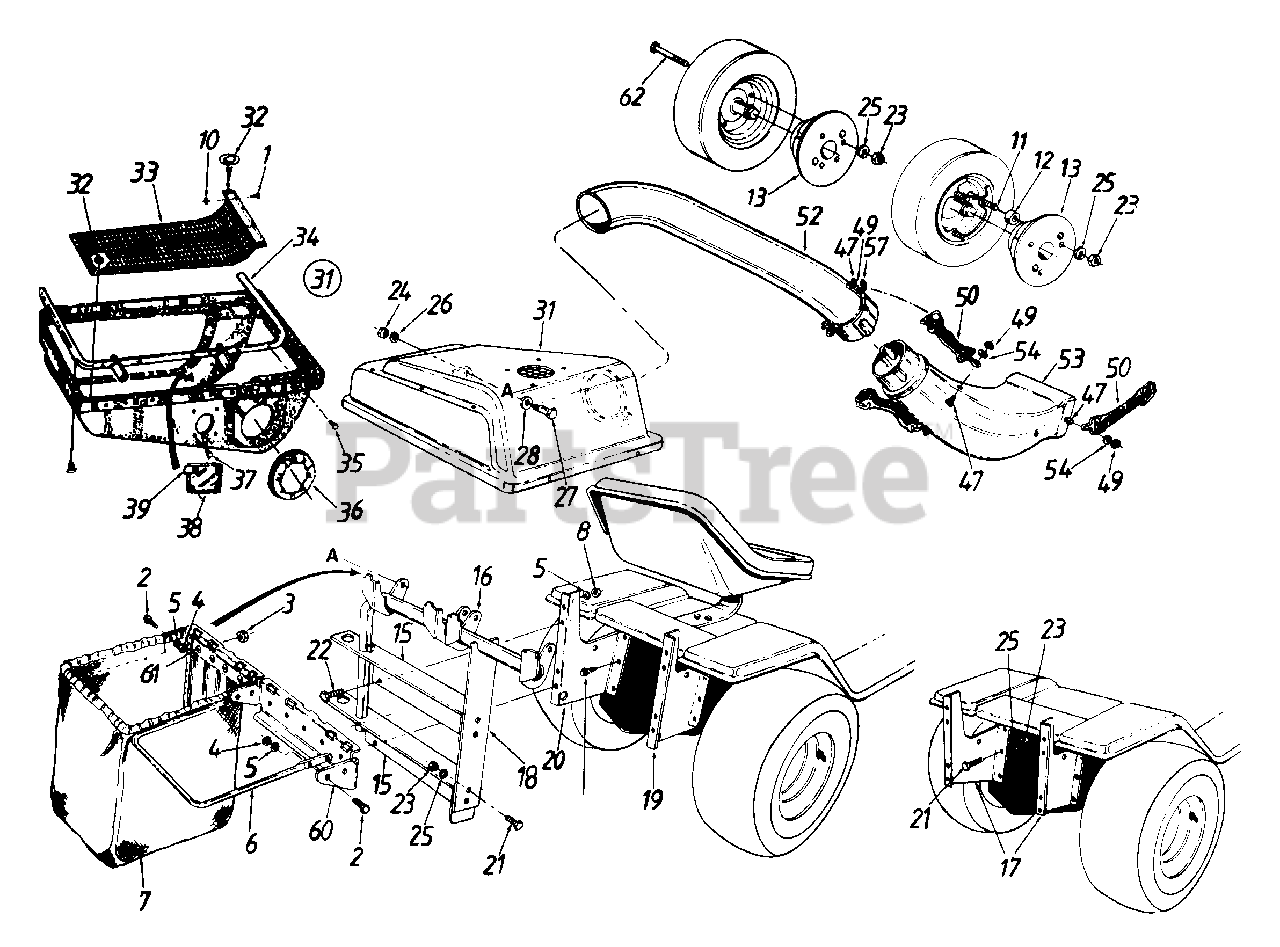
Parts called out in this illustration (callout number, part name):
1	Pop Rivet .188 Dia.
2	Hex Bolt 1/4-28 x .88" Lg.
3	Hex Sems Nut #10-24 Thd.
4	Hex Nut 1/4-28 Thd.
5	L-Wash. 1/4" I.D.
7	Grass Catcher Bag
8	Hex Nut 1/4-20 Thd.
10	Flat Wash. 1/4" I.D.
11	Wheel Weight Snap Ring
12	Spacer
22	Hex Bolt 1/4-20 x .62" - Gr. 5
23	Hex Nut 5/16-18 Thd.
24	Hex Nut 3/8-16 Thd.
25	L-Wash. 5/16" I.D.
26	L-Wash. 3/8" I.D.
27	Shld. Bolt 3/8-16 x .50" Dia.
28	Bell-Wash..505" I.D. x 1.0" O.D.
31	Grass Catcher Cover Ass'y.
32	Twist Fastener
35	Hex A6-Tap Scr. 1/4 x .62"
37	Truss B-Tap Scr. #10 x .5"
38	Plastic Plate
39	Speed Nut
47	Hex Bolt 1/4-20 x .625"
49	Hex Ins. L-Nut 1/4-20 Thd.
50	Retainer Strap Ass'y.
52	Catcher Tube
53	Discharge Chute
54	L-Wash..27" I.D.
57	Retainer Hook Brkt.
61	Truss Mach. Scr. #10-24 x .5"
62	Hex Bolt 5/16-18 x .4" Lg.
